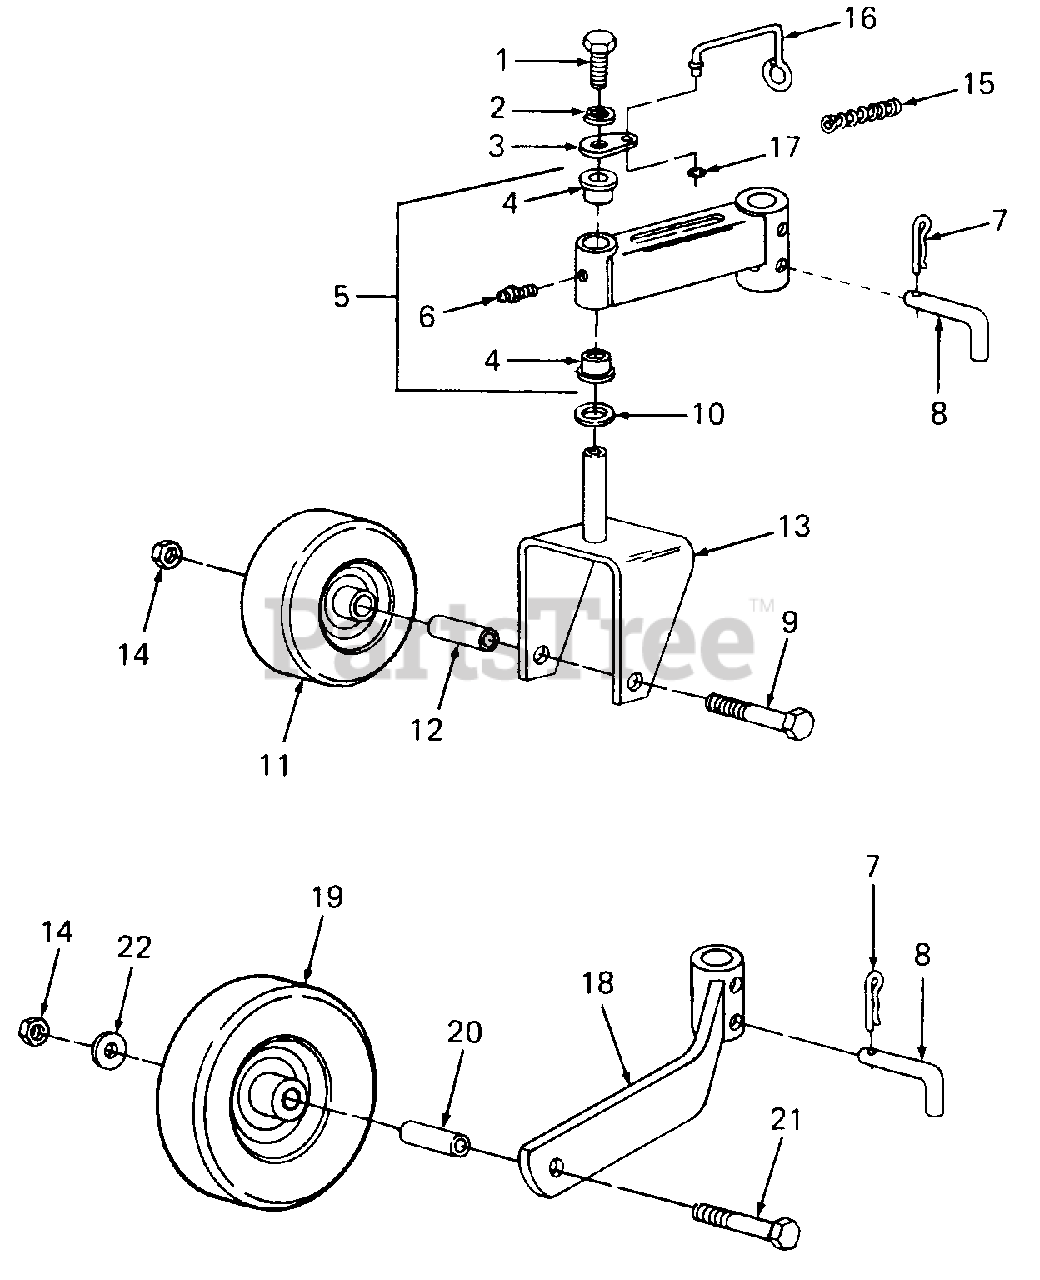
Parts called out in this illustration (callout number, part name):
1	Screw,Hex Cap, 3/8-16 X .75, Lg
2	Washer, Lock, 3/8
3	Bracket, Wheel Return
4	Bushing, Flange
5	Mounting Assy, Front Caster & Bushings
6	Fitting, Grease
7	Pin, Quick Attach
8	Pin, Wheel Axle
9	Screw, Hex Cap, 1/2-13 X 5.0 Lg GR5
10	Washer, Flat, .765 ID X 1.5 OD X .0598 Thk
11	Wheel, Front Gauge
12	Spacer, Wheel
15	Spring, Compression
16	Rod, Wheel Return
17	Ring, Push-on Retainer, 1/4
18	Bracket, Rear Gauge Wheel
19	Wheel, Rear Gauge, 8"
21	Screw, Hex Cap, 1/2-13 X 4.5 Lg GR5
22	Washer, Flat, 9/16 X 1-3/8 X .109
